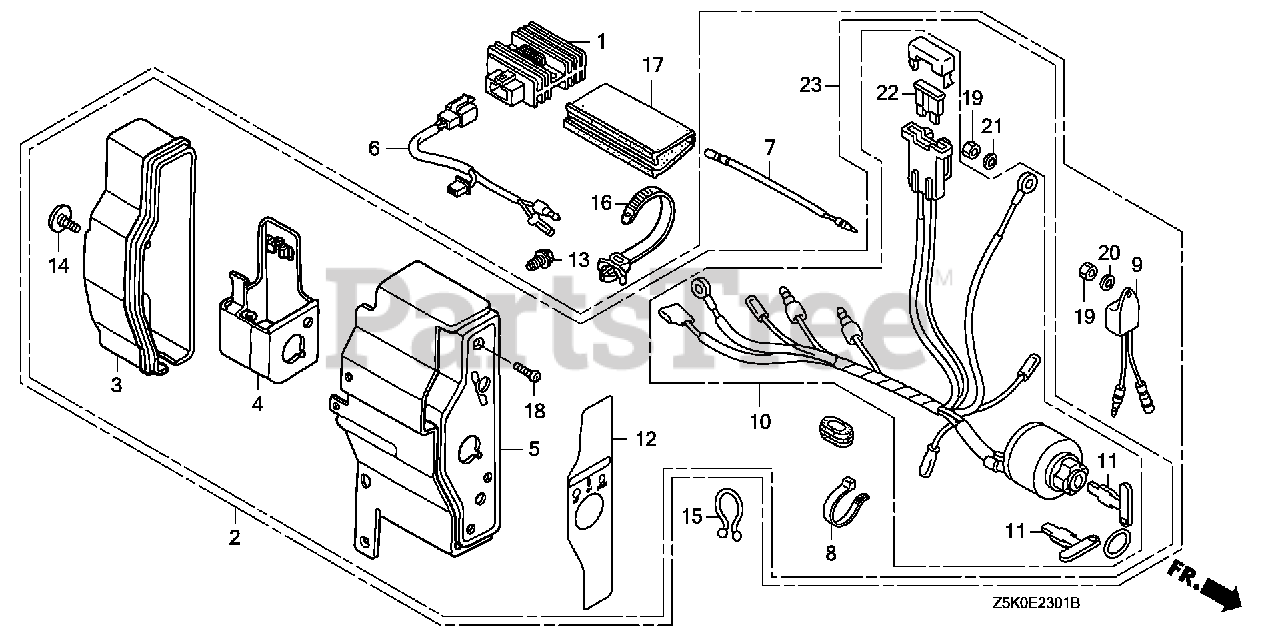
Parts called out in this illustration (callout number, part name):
3	CASE, CONTROL
4	BRACKET, CASE MOUNTING
5	PANEL, CONTROL *R280* (POWER RED)
8	BAND
10	SWITCH ASSY., COMBINATION (10A)
11	KEY
12	MARK, CONTROL BOX (EXP)
13	BOLT, FLANGE (6X12) (CT200)
14	SCREW, SPECIAL (6X12)
15	CLIP, PURSE LOCK
16	STRAP, CABLE (118MM) *NH1L* (Honda Code 1170653). (BLACK)
17	TUBE, FASTENER (30)
18	SCREW, PAN (4X12)
19	NUT, HEX. (4MM)
21	WASHER, SPRING (4MM)
22	FUSE, BLADE (15A)
23	BOX ASSY., CONTROL (10A) *R280* (EXP-ALERT) (POWER RED)
